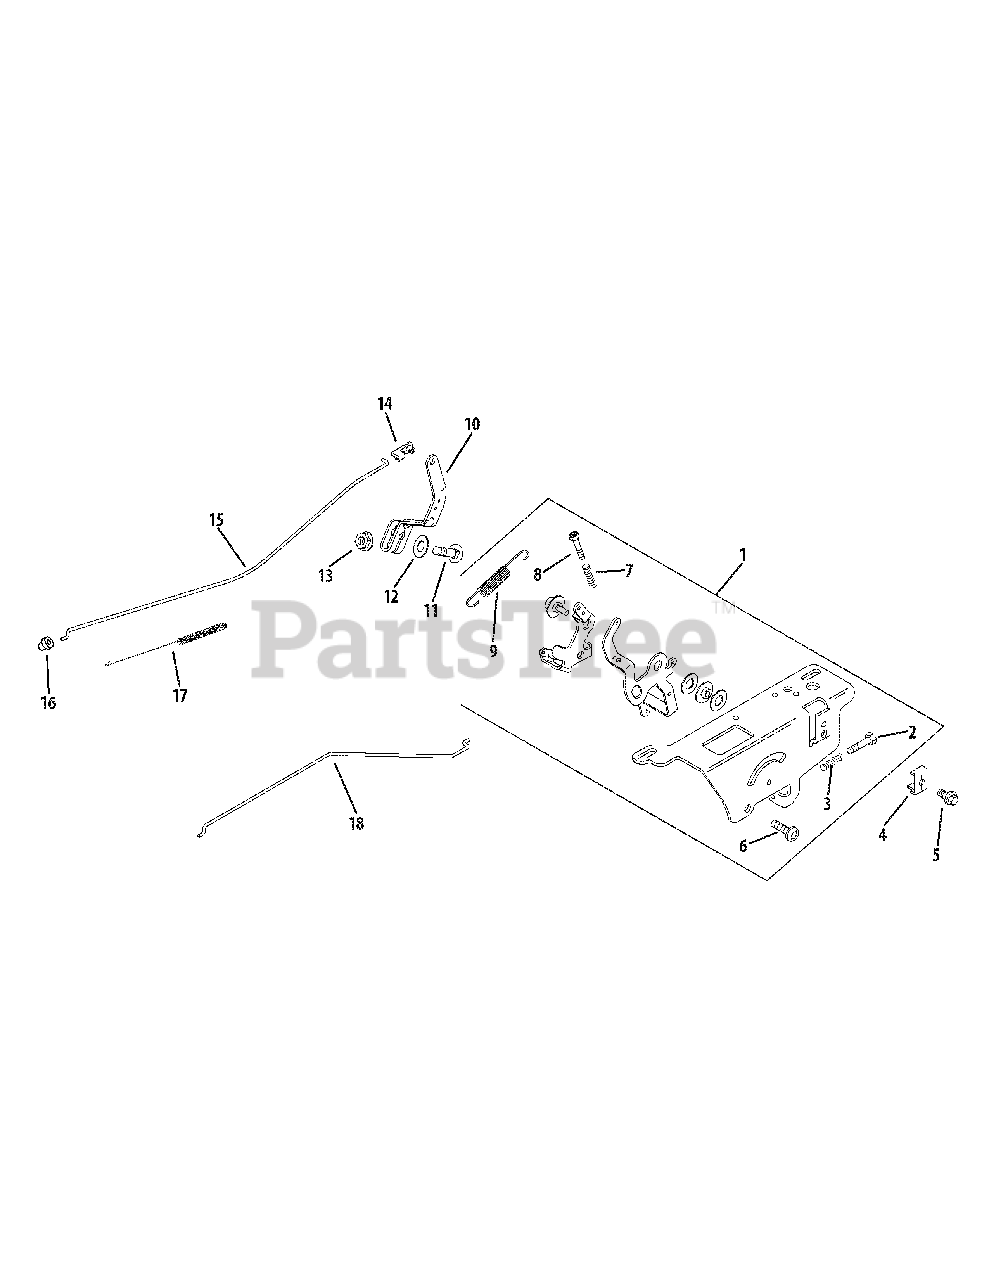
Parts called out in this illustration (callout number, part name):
1	Speed Cntrl. Ass. Kit (Inc. 2, 3 & 6-9)
2	Phl Thd Frm Screw, M4 X 0.7 X 25
3	Speed Control Spring (Short)
4	Cable Clamp
5	Flg Thd Frm Screw, M5 X 0.8 X 16
6	Lbd Skt Screw, M6 x 1.0 x 20
7	Speed Control Spring (Short)
8	Phl Thd Frm Screw, M4 X 0.7 X 25
9	Governor Spring
10	Governor Lever
11	Rd Hd Sq Nck Bolt, 1.4-20 X 1"
12	Internal Tooth Lock Washer, 1.4"
13	Hex Flange Nut, 1.4-20"
14	Throttle Linkage Bushing
15	Throttle Linkage
16	Linkage Retaining Bushing
17	Linkage Spring
18	Choke Linkage
